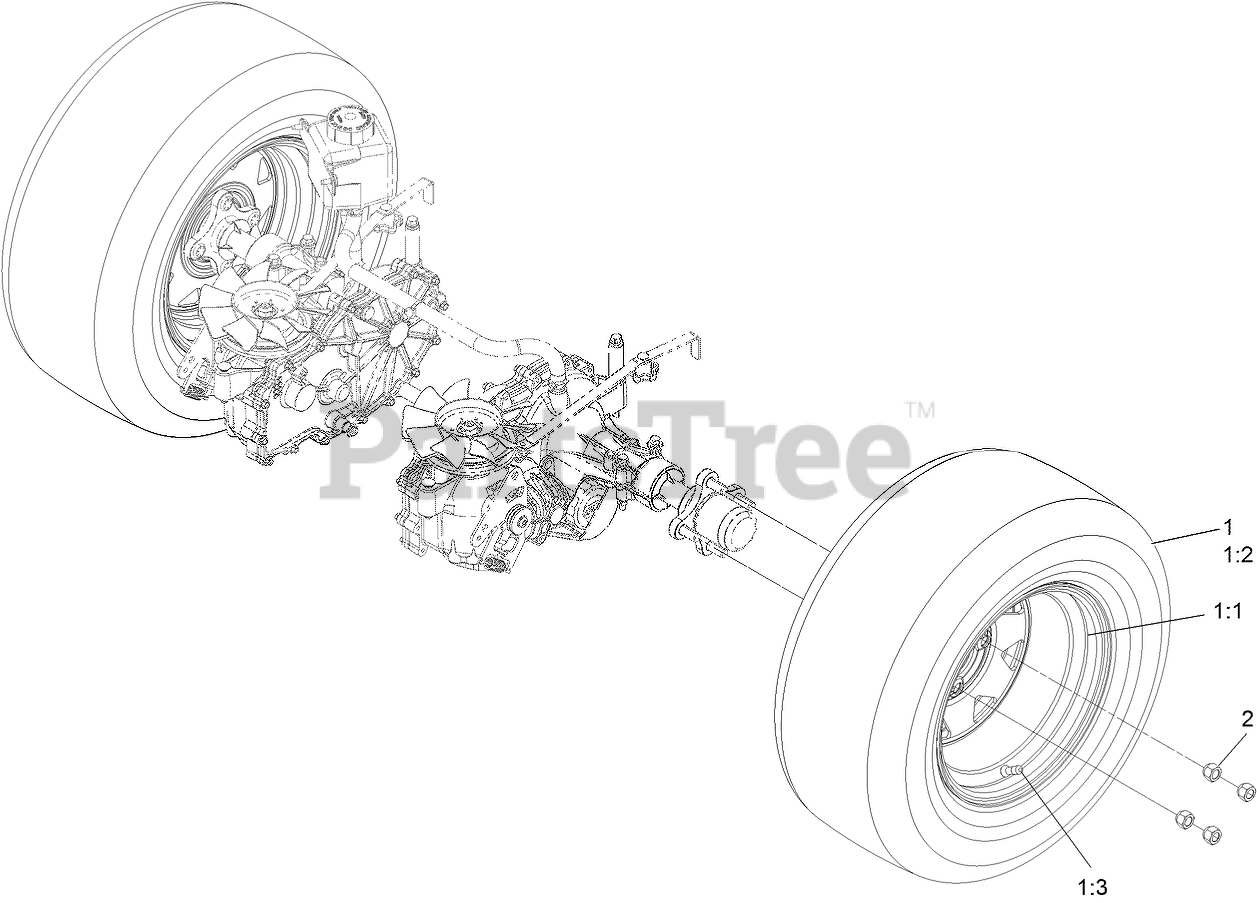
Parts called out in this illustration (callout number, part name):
1	WHEEL AND TIRE ASM
1:1	WHEEL-12X7, 8 SPOKE 4 ON
1:2	TIRE
1:3	Stem-Valve
2	NUT-LUG
